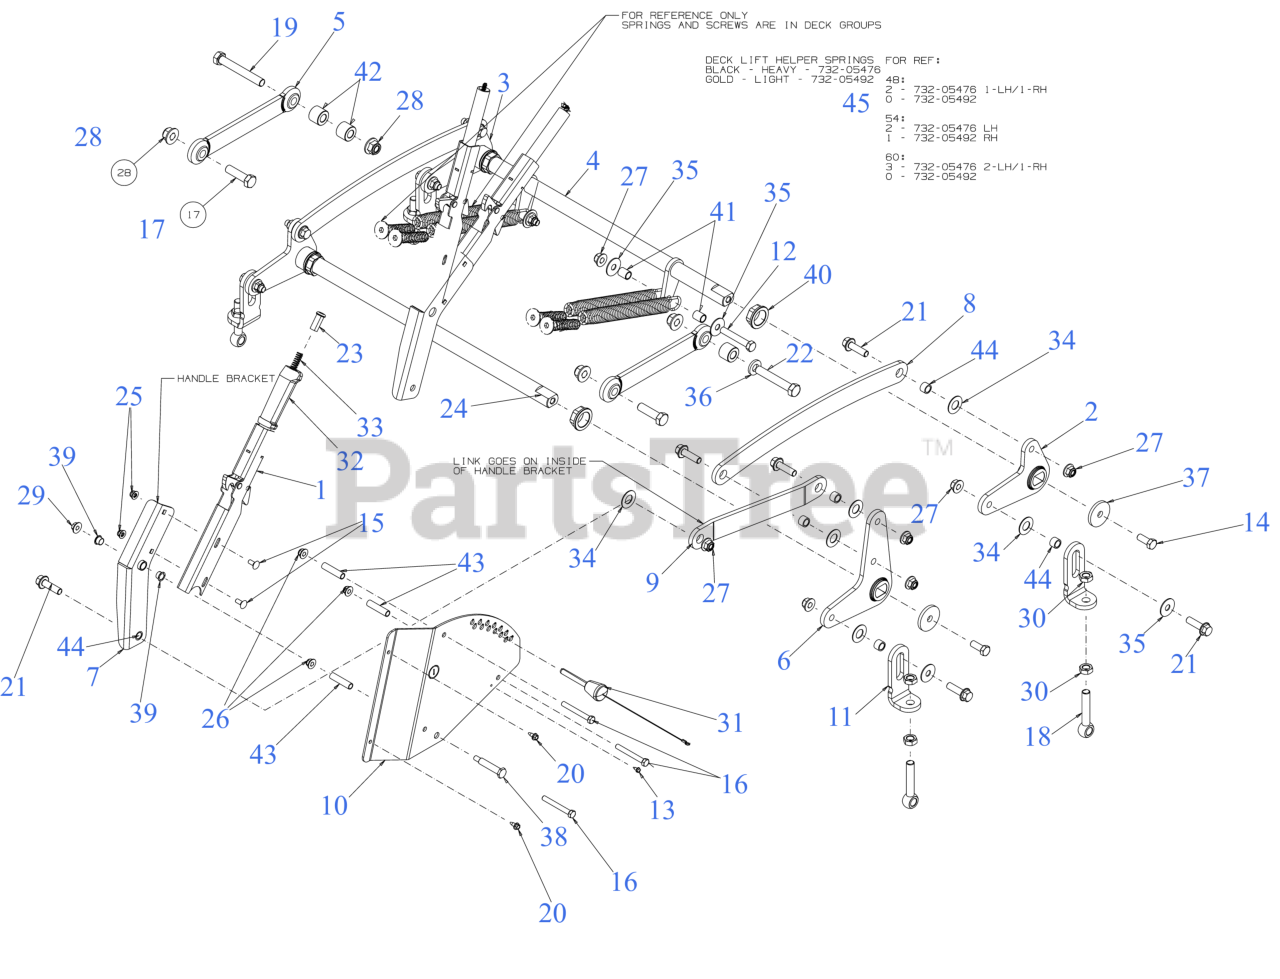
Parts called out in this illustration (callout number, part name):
1	LATCH HANDLE ASSEMBLY
2	DECK LIFT BELLCRANK ASSEMBLY (RH)
3	DECK LIFT BELLCRANK ASSEMBLY (LH)
4	DECK LIFT SHAFT
5	DECK CONTROL ROD
6	DECK LIFT BELLCRANK (RH)
7	DECK LIFT HANDLE
8	DECK LIFT LINK
9	DECK LIFT LINK
10	INDEX PLATE
11	ADJUSTMENT ARM
12	SCREW-HEX 1/2-13 x 3.00
13	HEX SCREW AB-TAP #10 x .50
14	SCREW 1/2-13 x 1.25 GR5
15	CARRIAGE BOLT 5/16-18 x .75
16	SCREW 3/8-16 x 3 GR8
17	SCREW 5/8-11 x 2.25 GR5
18	EYE BOLT 5/8-11 x 3.63
19	SCREW 5/8-11 X 4.5 GR5
20	SCREW 1/4-20X.625
21	FLANGE BOLT 1/2-13:1.75:GR5
22	SCREW 5/8-11 x 3.75 GR5
23	LIFT HANDLE BUTTON
24	DECK LIFT SHAFT
25	FLANGE LOCK NUT 5/16-18
28	FLANGE LOCK NUT
29	LOCK NUT 3/8-16
30	HEX NUT
31	MAGNETIC DECK LOCK KNOB
32	LIFT HANDLE GRIP
33	COMPRESSION SPRING
34	FLAT WASHER
35	WASHER .51 x 1.5 x .07
36	FLAT WASHER .635 x 1.24 x .181
37	FLAT WASHER .53"x2.125"x.25"
38	SHOULDER SCREW .50 x 2.23 3/8-16
39	NYLINER BEARING
40	FLANGE BEARING
41	SPACER 0.535 x 0.68 x 0.83
42	SPACER 0.630x1.25x1.00LG
43	SPACER .38 ID x .50 OD x 2.06 LG
44	SPACER
45	EXTENTION SPRING 1.20 x 11.35
45	EXTENSION SPRING 1.44 OD x 11.36
